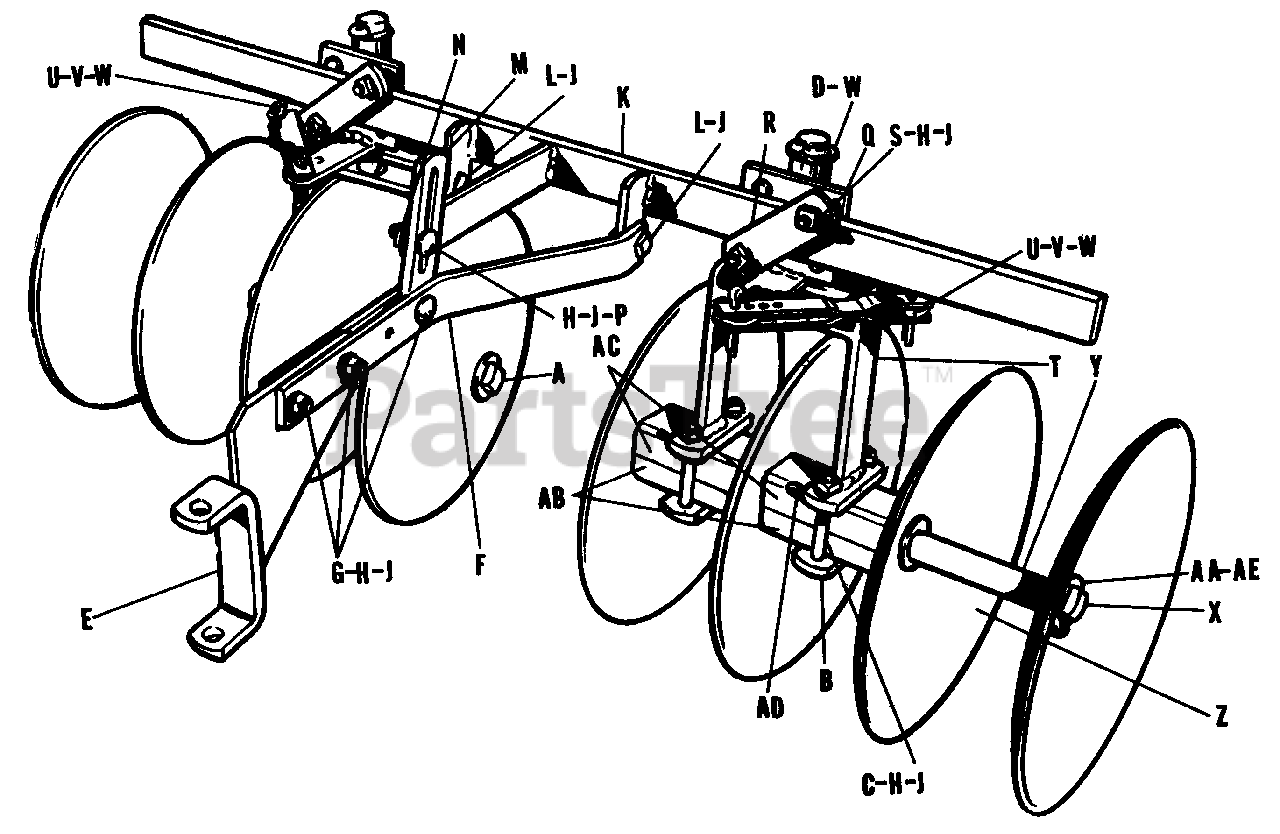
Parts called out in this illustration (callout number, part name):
A	Nut, Full Hex., 5/8-11 NC
B	Clip, Bearing
C	Bolt, Carriage, 3/8-16 NC x 3 1/4" lg.
D	Washer, Post
E	Drawbar End
F	Bar, Draw
G	Bolt, Carriage, 3/8"-16 NC x 1 1/4" lg.
H	Washer, Lock 3/8"
J	Nut, Full Hex., 3/8"-16 NC
K	Bar Assembly, Cross
L	Screw, Cap, Hex ., 3./8"-16 NC x 1" lg.
M	Link, Tilt Adjusting
P	Bolt, Carriage, 3/8"-16 NC x 1" lg.
Q	Clamp Assembly
R	Clamp, Clip
S	Bolt, Carriage, 3/8"-16 NC x l 3/4" lg.
T	Arch Assembly
U	Strap Assembly, Adjusting
W	Pin, Cotter
Y	Spacer, Disc.
Z	Blade, Disc. 12"
AA	Washer, Special
AB	Block, Lower Bearing
AC	Block, Upper Bearing
AD	Pin, Cotter, 3/16" x 3/4" lg.
AE	Washer, Lock
